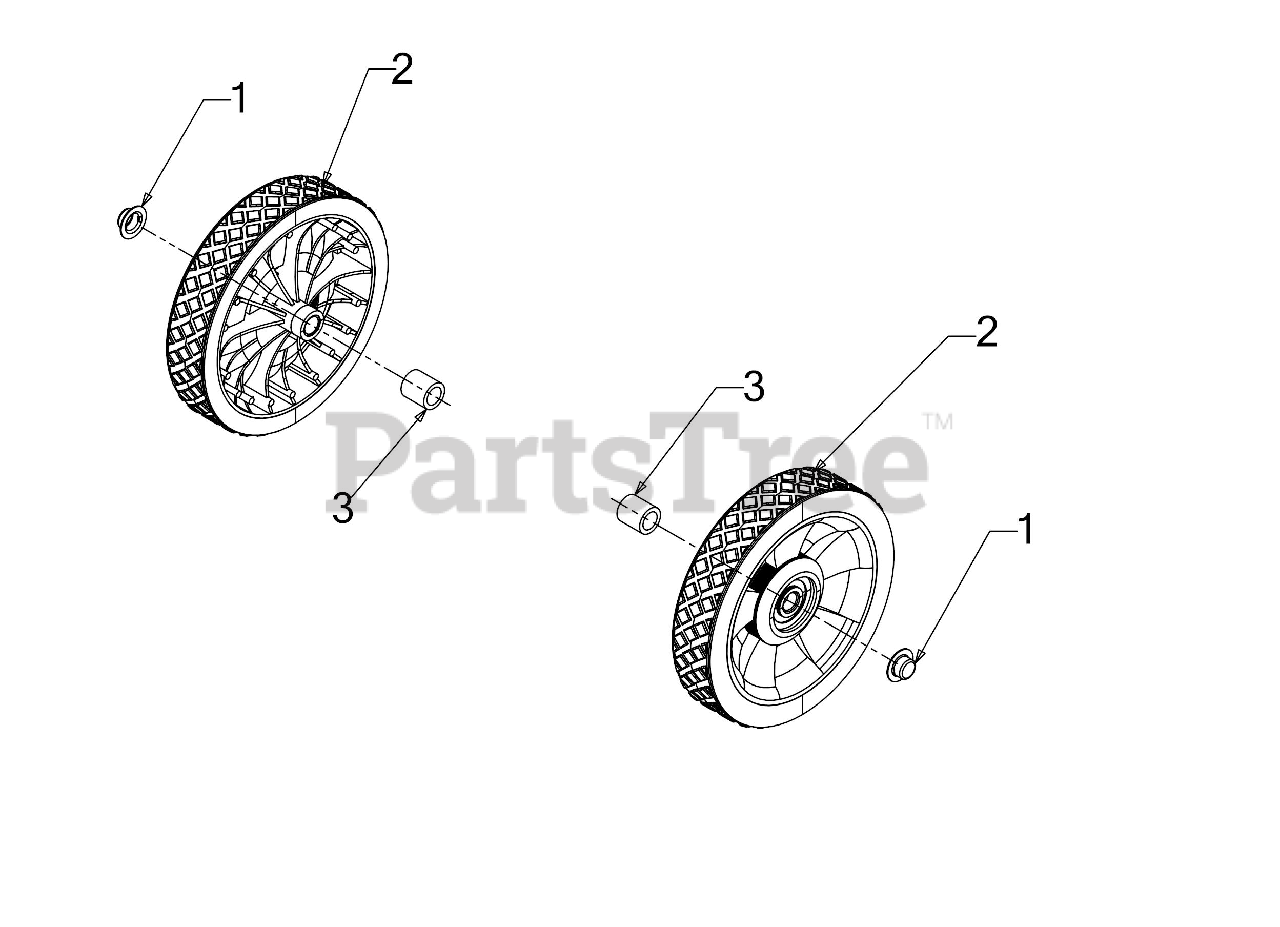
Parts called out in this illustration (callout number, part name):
1	PUSH CAP
2	COMPLETE WHEEL
3	SPACER .525 x .775
